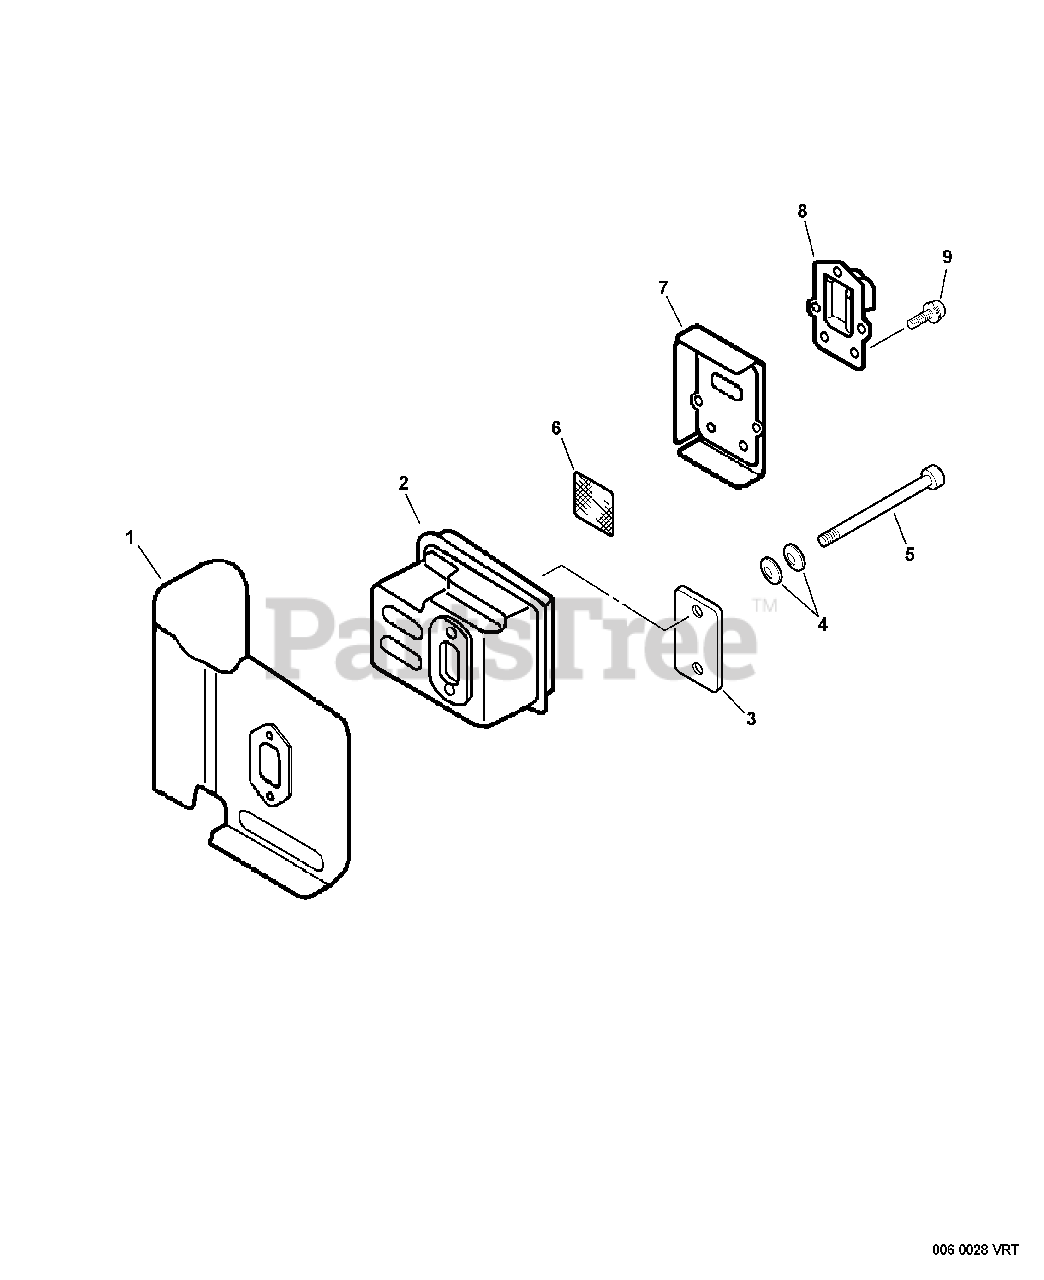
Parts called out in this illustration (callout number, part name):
1	HEAT SHIELD, EXHAUST
2	MUFFLER
3	PLATE, EYE
4	CONICAL WASHER
5	BOLT 5×55
6	SCREEN, SPARK ARRESTER
7	GASKET, EXHAUST
8	GUIDE, EXHAUST
9	SCREW 4×10
